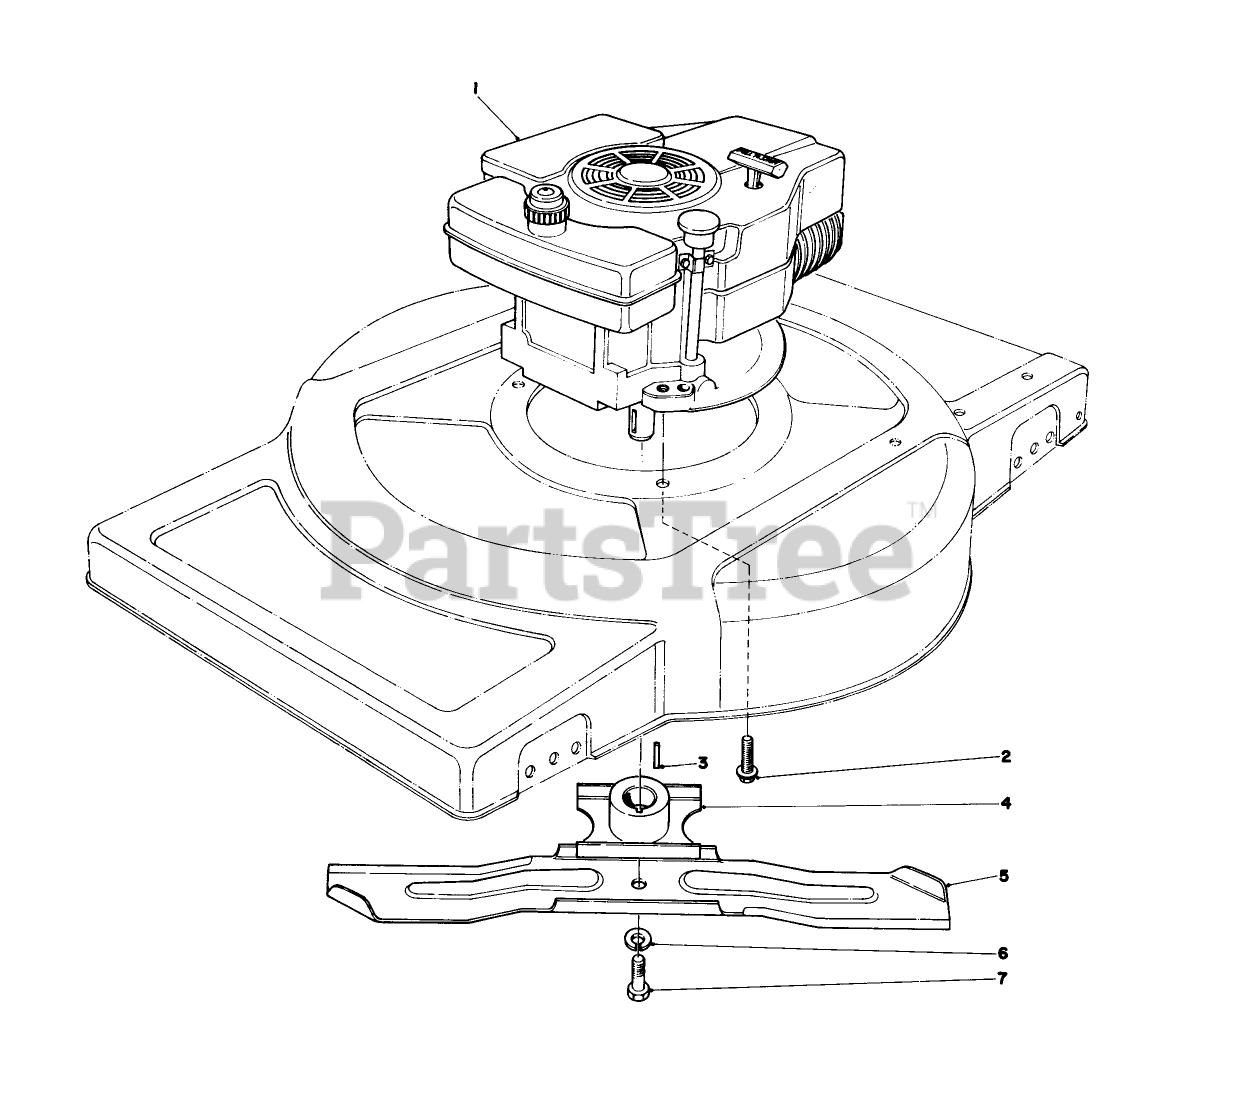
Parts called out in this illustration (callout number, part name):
1	Engine
2	SCREW-HWHTF
3	KEY-SQUARE
4	BLADE RETAINER WA(BLACK)
5	Blade
6	WASHER-LOCK
7	BLADE SCREW
